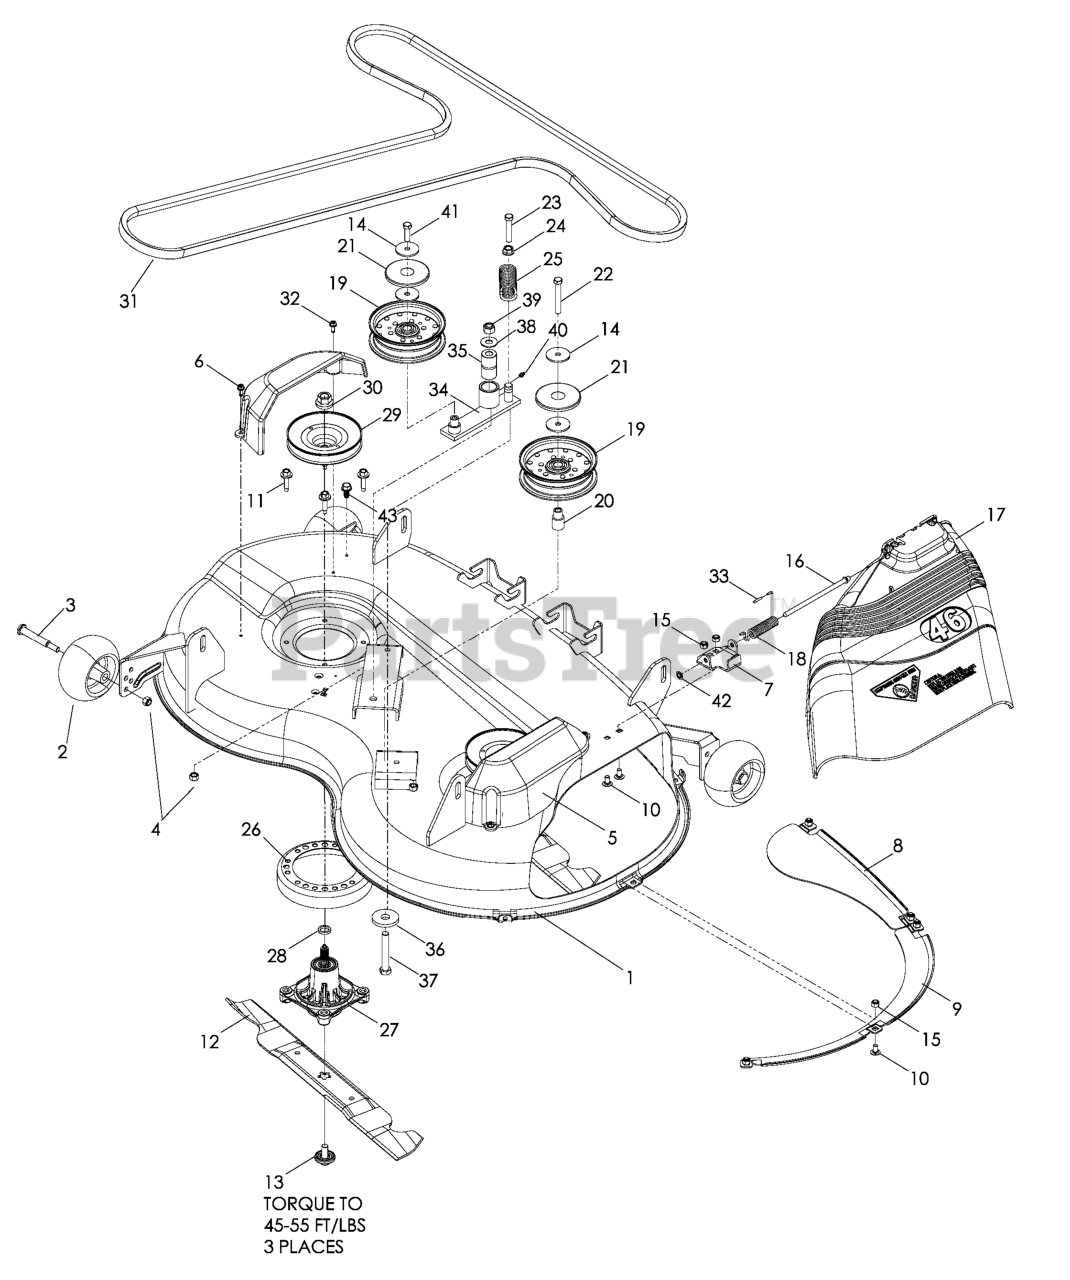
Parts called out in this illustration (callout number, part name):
1	DECK W/DECALS 46" ORANGE
2	GAUGE WHEEL
3	SHOULDER BOLT 1/2X2-5/8 ZD SPE
4	NUT 3/8-16 NYLOC
5	COVER.MANDREL.RH.46"
6	COVER.MANDREL.LH.46"
7	BRKT.DEFLECTOR.38"2005+
8	BAFFLE CENTER FRONT
9	BAFFLE FRONT RH
10	CARRIAGE BOLT 5/16C X 5/8"
11	WASHER HEAD SCREW
12	BLADE, 46" HI-LIFT
13	BOLT.WASHER.ASM.7/16-2
14	WASHER, 3/8 SPEC
15	NUT 5/16 NYLOC
16	ROD, HINGE
17	SHIELD.DEFLECTOR.MOWER.46"BLAC
18	TORSION SPRING
19	IDLER PULLEY
20	IDLER BUSHING
21	TOP DUST CAP
22	HEX SCREW 3/8-20 X 2.75
23	HCS 3/8C X 2
24	NUT 3/8C WHIZ
26	STRIPPER-ROUND-UNIVERSAL
27	CUTTER HOUSING
28	WASHER-SPACER
29	RP.PULLEY, DECK
30	LOCKNUT - 9/16
31	BELT, DECK
32	SCREW- 1/4-20 X 5/8
33	CAP-SLEEVE
35	PIVOT BUSHING
36	WASHER, SUPPORT
37	HCS 1/2C X 3 1/4
38	WASHER 1/2 FLAT
39	NUT 1/2-13 HEX NYLOC ZD
40	ZERK
41	HCS 3/8C X 1 1/4 GR5
42	PUSH NUT
43	SCREW, 3/8-16 X 3/4 THREAD CUT
